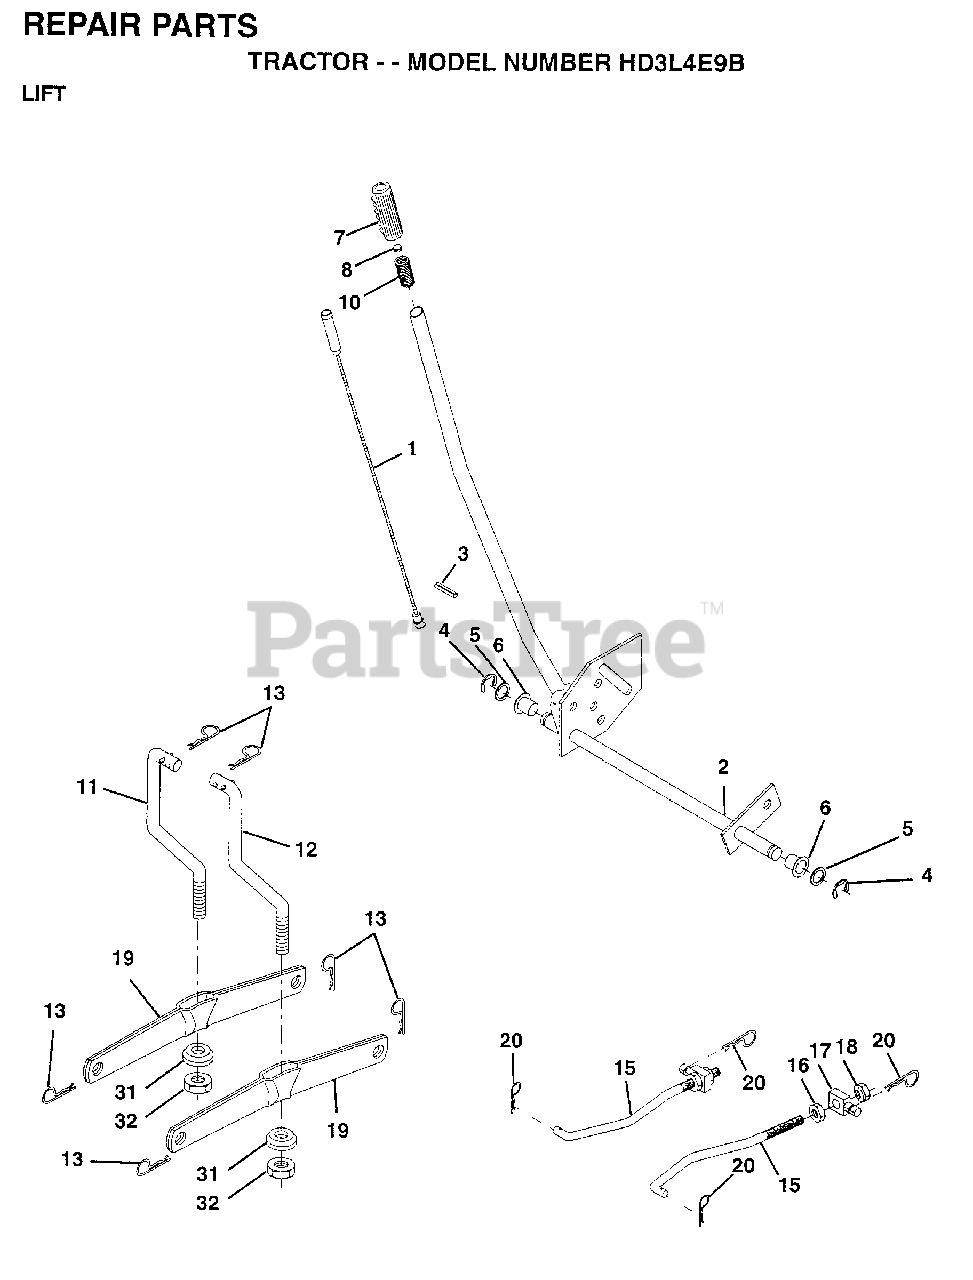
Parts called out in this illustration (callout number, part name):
1	WIRE ASM
2	HANDLE.LIFT.LH.
3	PIN GROOVE
5	WASHER
6	NYLON BEARING
7	GRIP
15	LINK.FRONT
16	NUT
17	TRUNION
18	NUT.LK.W/WSH.1/2.
19	ARM SUSP REAR
20	RETAINER.SPRING
31	BEARING PVT LH
32	NUT.CROWNLOCK.3/8
